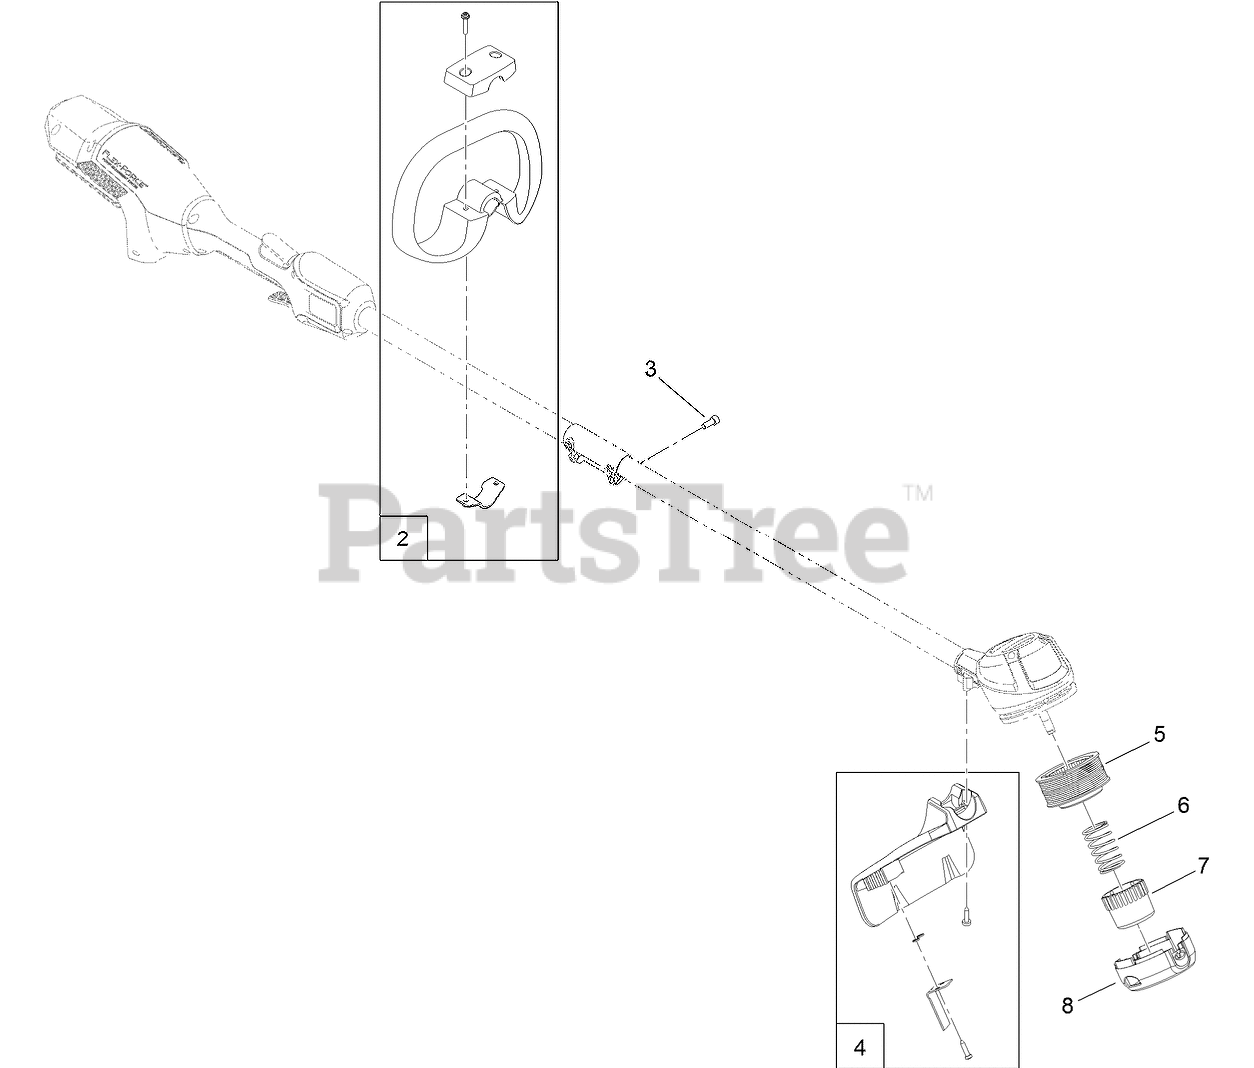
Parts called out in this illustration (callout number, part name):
2	HANDLE-TRIMMER
3	SCREW-COUPLER, SHAFT
4	SHIELD-GRASS
5	LINE-TRIMMER
6	SPRING-FEED, BUMP
7	BUTTON-FEED, BUMP
8	COVER-SPOOL
